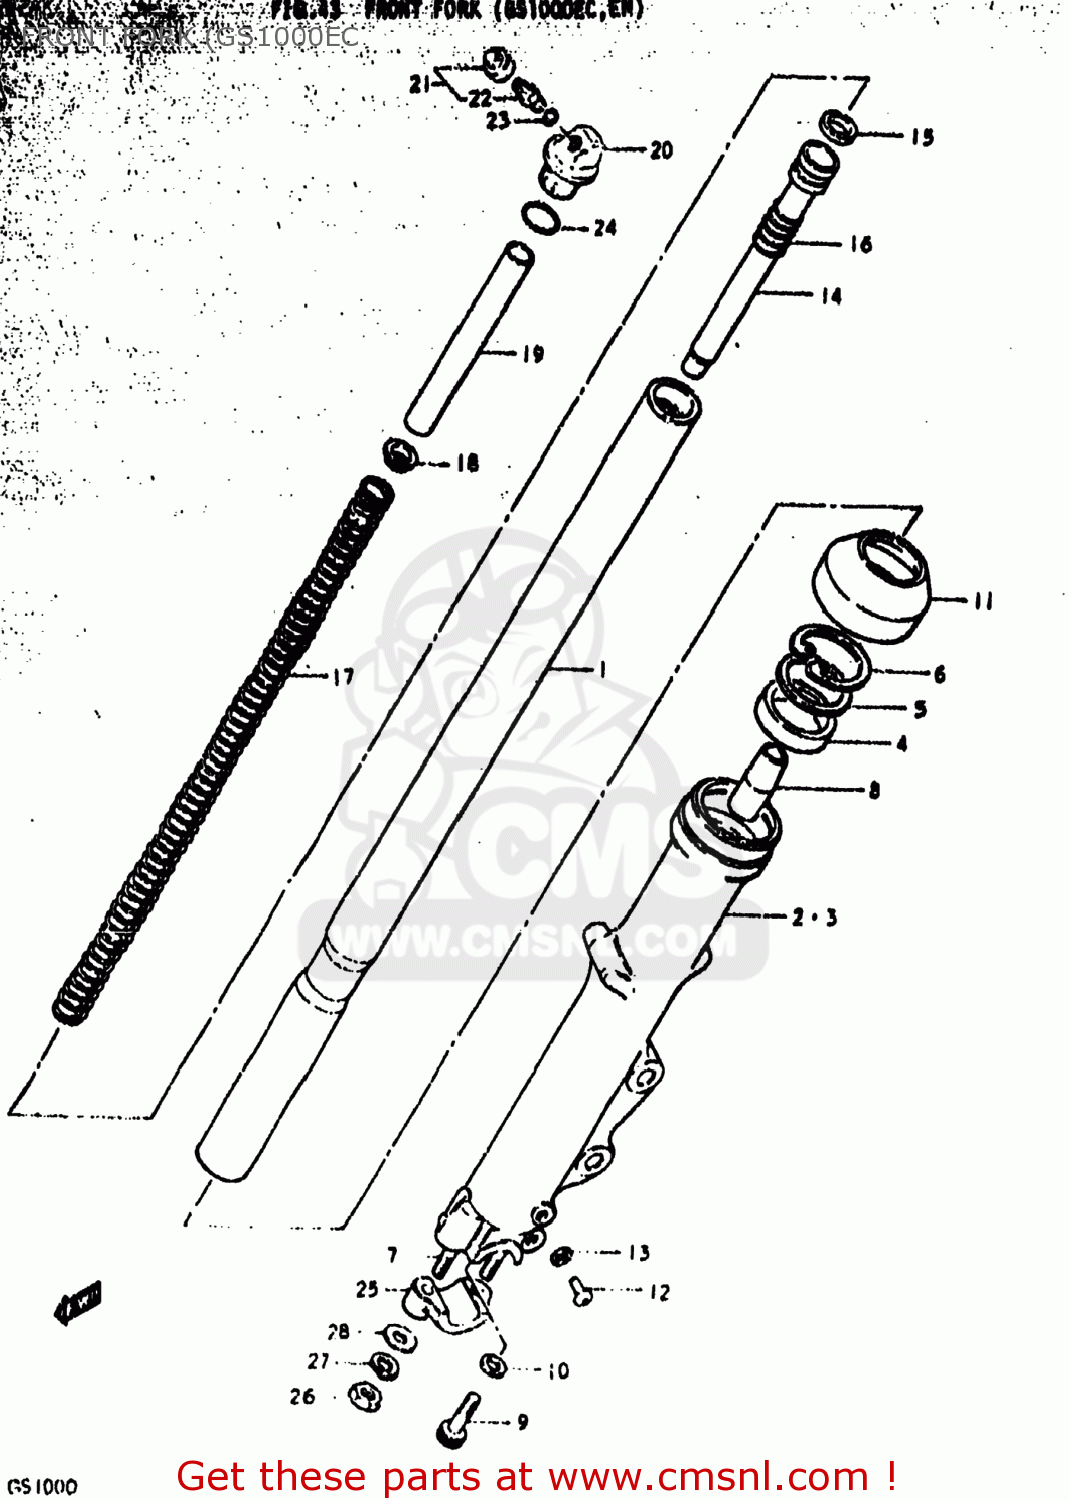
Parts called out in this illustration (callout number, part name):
0	DAMPER SET
1	TUBE,FORK,INNER
2	TUBE,FORK,OUTER,RIGHT
3	TUBE,OUTER,LEFT
4	OIL SEAL,FRONT FORK
5	WASHER. FRONT FORK
6	CIRCLIP,FORK OIL SEAL
7	STUD BOLT
8	PIECE,OIL LOCK
9	BOLT,FORK CYLINDER(10X25)
10	GASKET (NAS)
11	SEAL,DUST
12	SCREW
13	GASKET,DRAIN,PLUG (NAS)
14	CYLINDER,FRONT FORK
15	RING,PISTON
16	SPRING,REBOUND
17	SPRING,FRONT FORK
18	GUIDE,FRONT FORK SPRING C
19	SPACER,FRONT FORK SPRING
20	CAP
21	VALVE & CAP ASSY
22	VALVE
23	O RING
24	O RING
25	HOLDER,AXLE
26	NUT (8MM)
27	LOCK WASHER
28	WASHER
